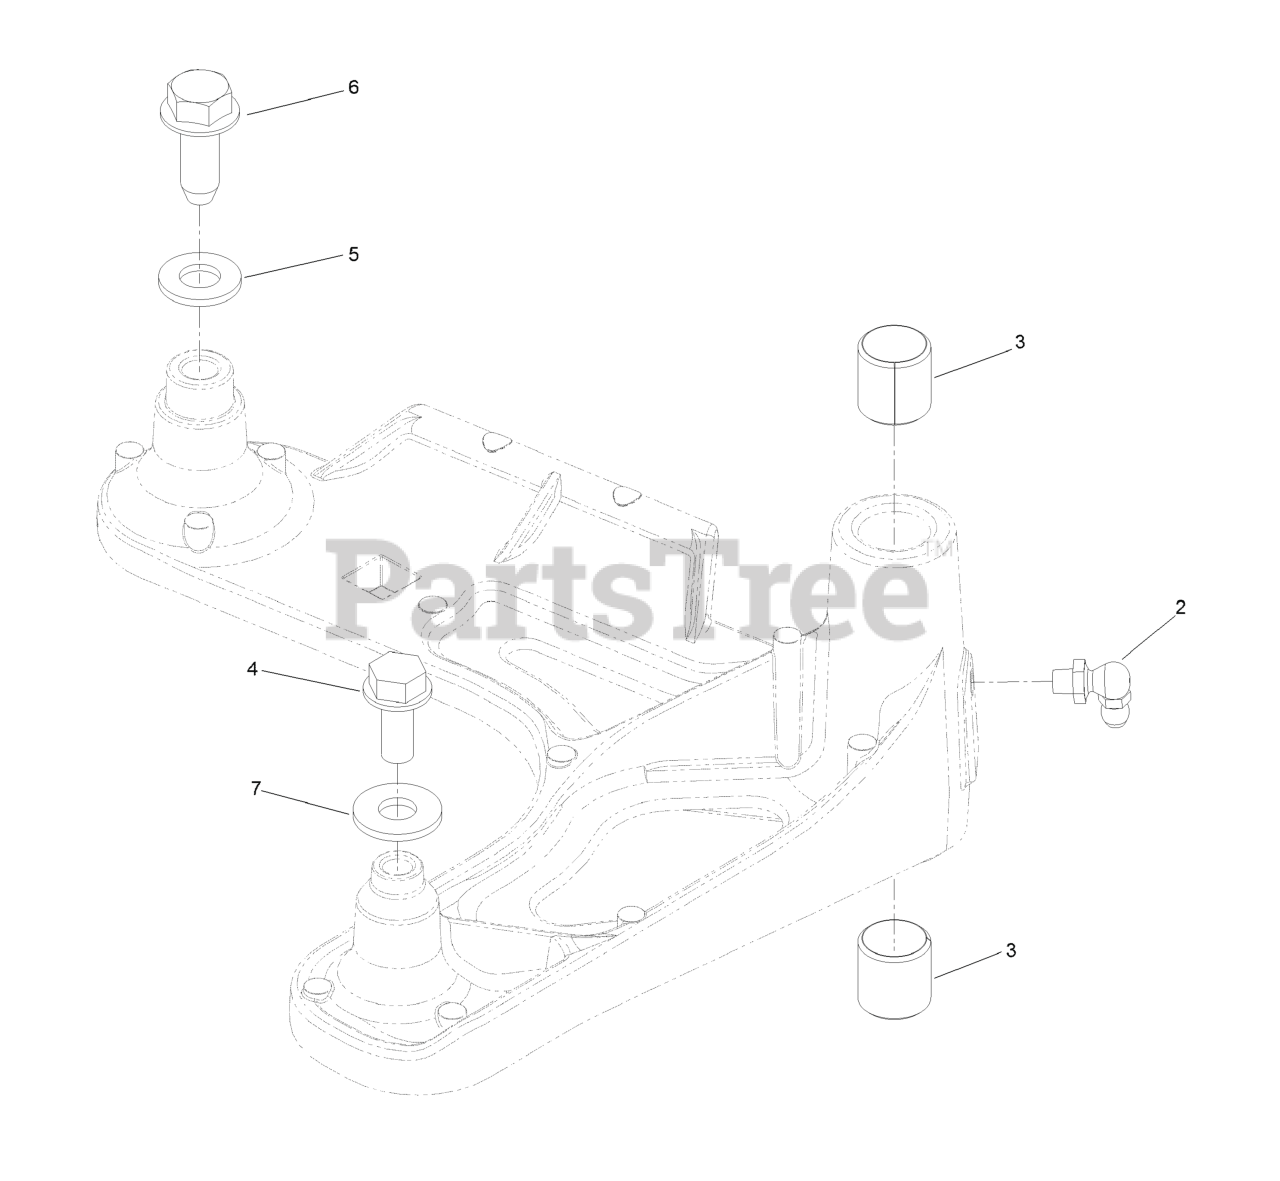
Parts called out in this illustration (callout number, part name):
2	FITTING-GREASE, 90 DEG
3	SLEEVE-BEARING
4	SCREW-THD ROLL, HWH
5	WASHER-FLAT
6	SCREW-FORMING, THREAD
7	WASHER-FLAT
